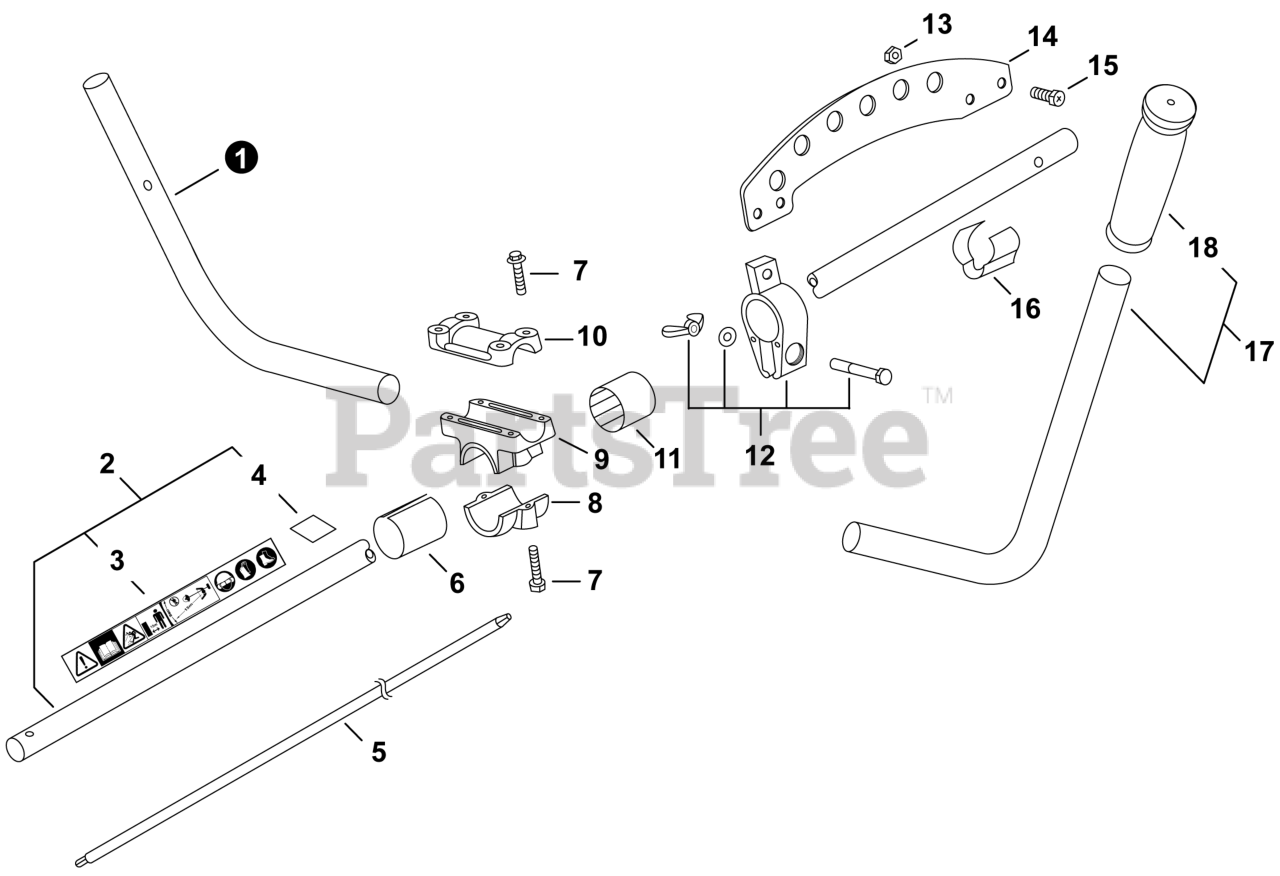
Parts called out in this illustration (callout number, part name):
1	HANDLE, RIGHT
2	MAIN PIPE ASSY
3	LABEL - CAUTION - ISO
5	DRIVESHAFT
8	BRACKET, MOUNTING
9	BRACKET, LOWER
10	BRACKET, UPPER
12	CLAMP ASSY
15	BOLT M6
16	HOLDER, CABLE
17	HANDLE ASSY, LEFT
